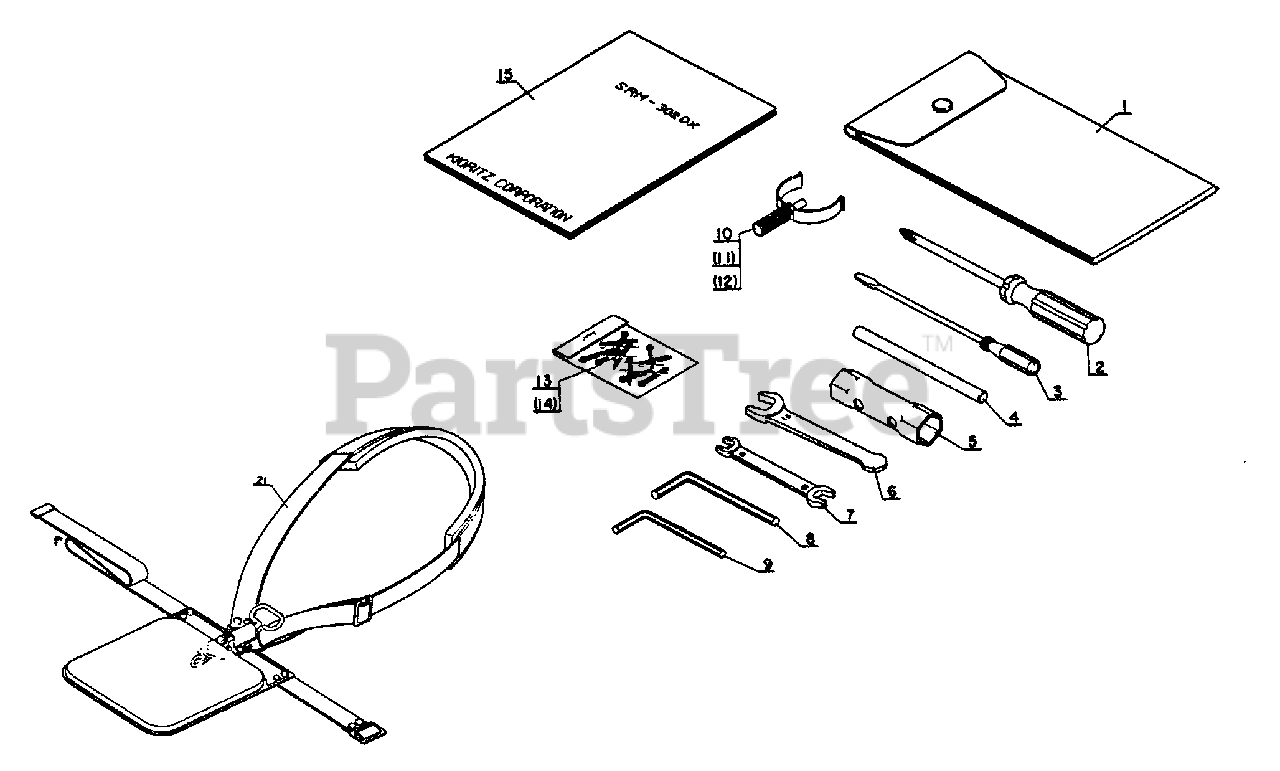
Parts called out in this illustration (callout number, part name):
1	BAG, TOOL
2	SCREWDRIVER - CROSS HEAD
3	SCREWDRIVER, SLOTTED
4	ROD, HANDLE
5	WRENCH 17×19
6	SPANNER 13
7	SPANNER 8×10
8	WRENCH, ALLEN 4 MM
9	WRENCH, ALLEN 3 MM
10	FITTING TOOL
13	PIN, COTTER 2×22 (PKG. OF 10)
15	OWNER'S MANUAL
21	SHOULDER STRAP ASSY
